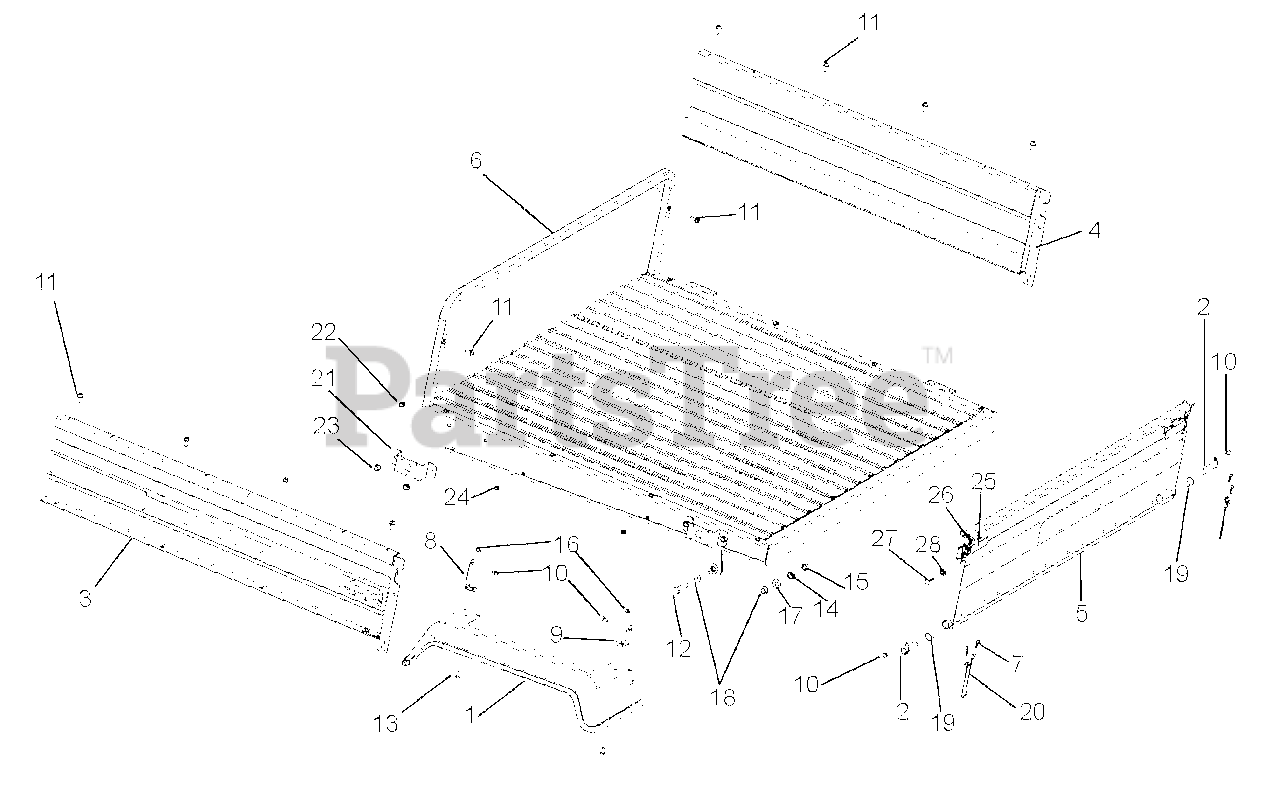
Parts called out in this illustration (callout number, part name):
1	FENDER BLACK UNIVERSAL TRUCK
2	WELDMENT, TAILGATE PIVOT
3	KIT, LEFT HAND BED SIDE 4 X 2 Includes Decals (996123, 125)
4	KIT, RIGHT HAND BED SIDE 4 X 2 Includes Decals (996123, 125)
5	KIT, TAILGATE Includes Decals, Latch & Bushings (996123, 125, 146)
6	BED BASE SUB-ASSEMBLY, BLACK
7	PIN, HAIR INTERNAL .08 X .18 X 1.18
8	BRACKET, FENDER MOUNT FRONT
9	BRACKET, FENDER MOUNT REAR
10	SCREW HEX SELF-TAP 1/4-20 X 1/2
11	BOLT, SERHFWH .312-18 X .75 YWZC
12	HFS 1/2-13 X 2 1/4 GR5 PLT
13	BOLT, SERHFWH .312-18 X .75 YWZC
14	NUT, LOCK CENTER .50-13 YWZC
15	NUT, JAM .50-13 GR5
16	NUT, LOCKING TOP FLANGE .25-20 YWZC
17	WASHER, FLAT STEEL .531 X 1.06 X .095 YWZC
18	BUSHING, 1/2ID X 5/8OD X 1/2 FLANGE
19	BUSHING, .75D X .625ID X 1.5L WITH FLG
20	TAILGATE CABLE
21	BRACKET, TREKER, STAKE POCKET
22	NUT, LOCKING NYLON .38-16 YWZC
23	BOLT, SERRATED HEX FLANGE WASHER HEAD .38-16 X .75
24	BOLT, SCREW HEX FLANGED WHIZ LOCK HEAD .25-20 X .62
25	LATCH, TAILGATE
26	SPACER, LATCH
27	BOLT-ROUND HEAD SQUARE NECK 10-24X.75 GRADE 5 Y
28	NUT-LOCKING-NYLON 10-24 with Insert
